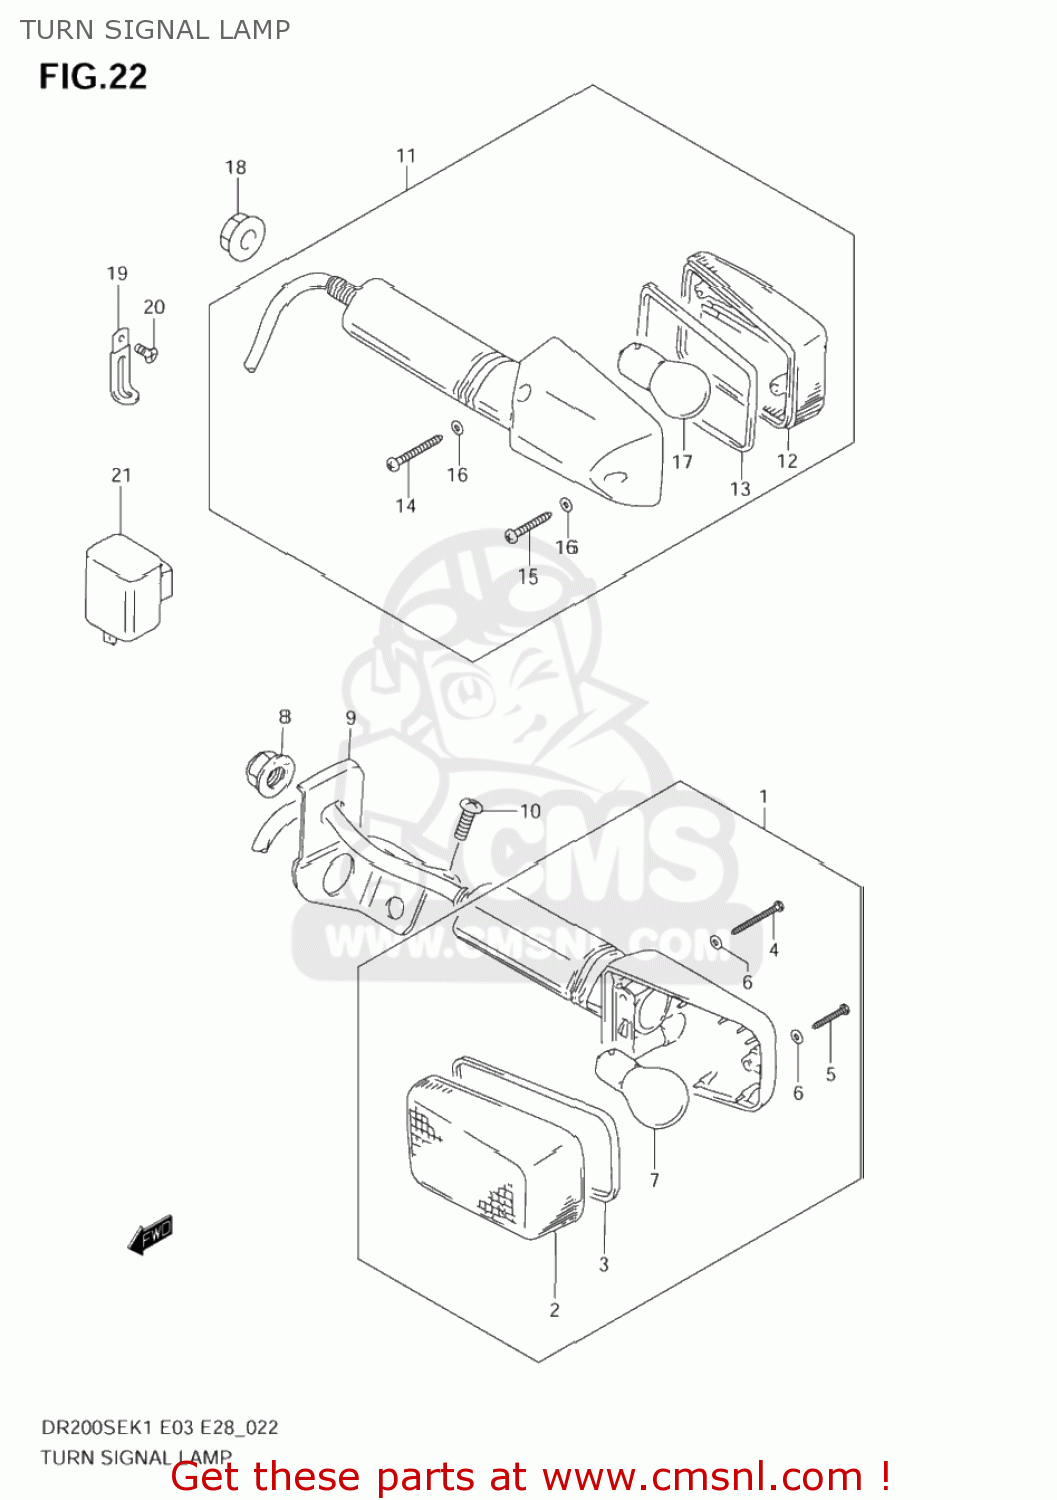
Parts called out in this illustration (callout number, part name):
1	LAMP ASSY,FR TURN SIGNAL
2	LENS
3	GASKET (NAS)
4	SCREW(3X30)
5	SCREW
6	GASKET (NAS)
7	BULB(12V21W)
8	NUT
9	BRACKET,FR TURN,R
10	SCREW
11	LAMP ASSY,RR TURNSIGNAL
12	LENS
13	GASKET (NAS)
14	SCREW(3X30)
15	SCREW
16	GASKET (NAS)
17	BULB(12V21W)
18	NUT
19	CLAMP(L:65)
20	SCREW
21	RELAY ASSY,TURNSIGNAL
